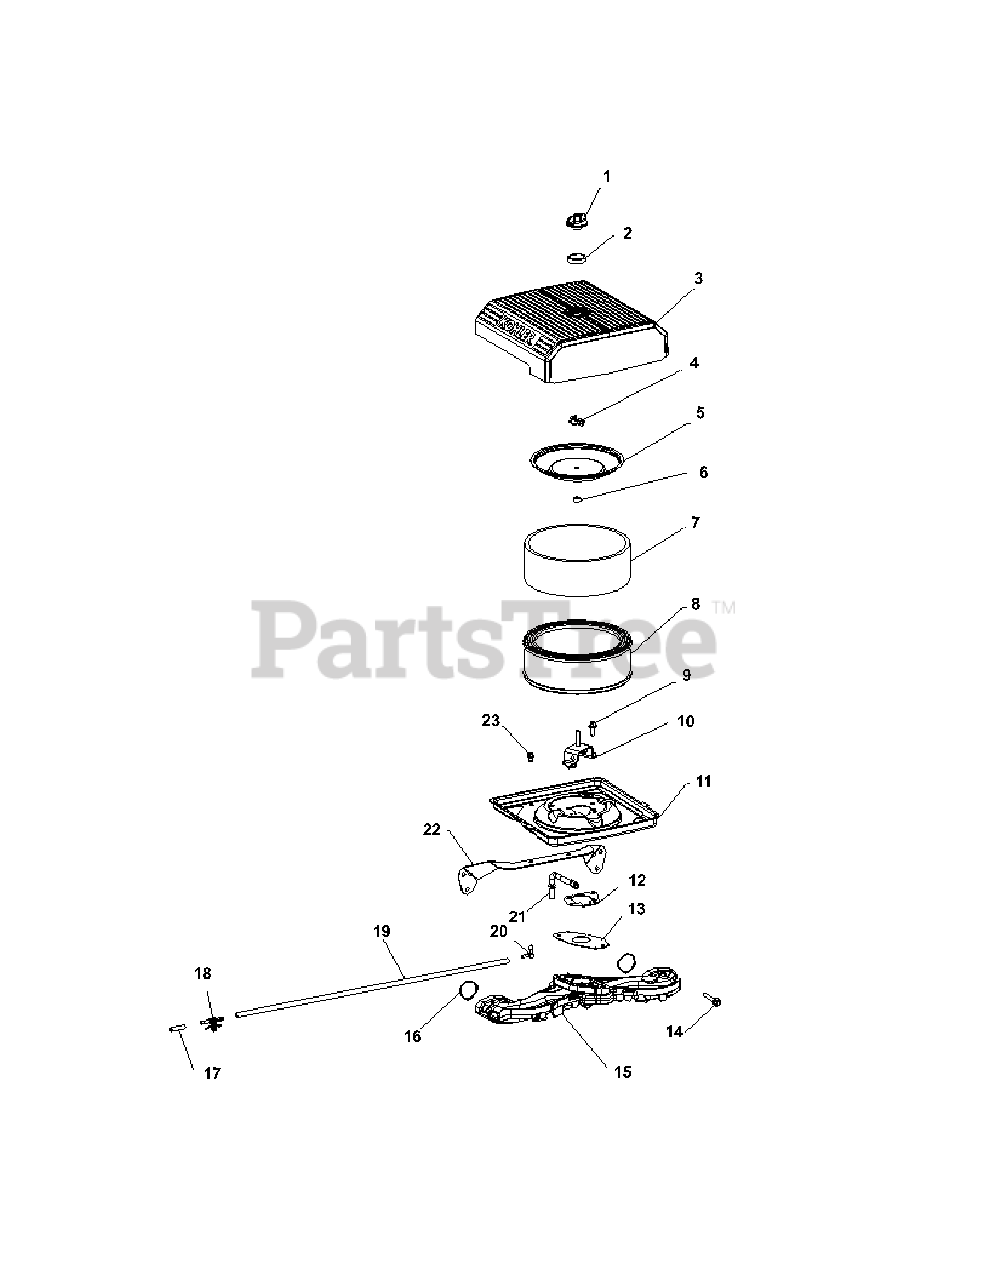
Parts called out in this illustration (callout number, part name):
3	Cover, Air Cleaner
5	Cover, Inner Air Cleaner
6	Seal, Inner Air Cleaner
7	Element, Precleaner (Low)
8	Elements, Air Cleaner Filter and Precleaner
9	Screw, Flg Thd Frm M6X1.0X16
10	Bracket, Air Cleaner
11	Kit, Air Cleaner Base
12	Gasket, Air Cleaner Base
13	Gasket, Carburetor
14	Screw, Flg M6X1.0X40
15	Kit, Intake Manifold
16	O-Ring, Intake Port
18	Connector, Evaporative
19	Hose, Evaporative, 20''
20	Connector, Evaporative Hose
21	Hose, Evaporative
22	Bracket, Air Cleaner Base
23	Screw, Flg Thd Frm M5X.8X10
